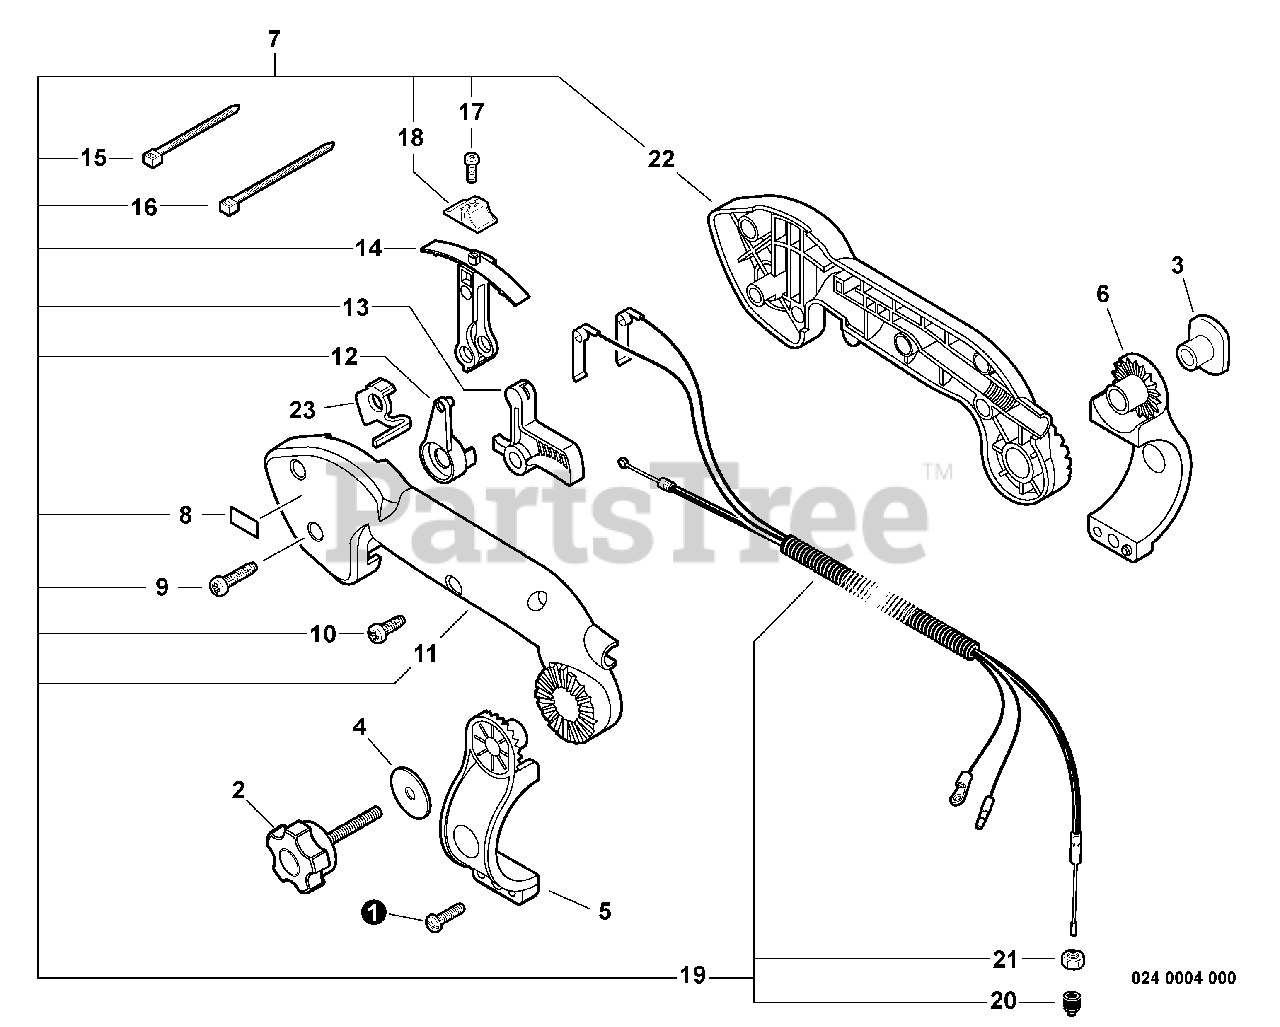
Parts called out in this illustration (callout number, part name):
1	SCREW, TAPPING 5×20
2	KNOB, SCREW
5	BRACKET, HANDLE - LEFT
6	BRACKET, HANDLE - RIGHT
7	CRUISE CONTROL KIT
8	LABEL, CAUTION - IDLE
11	HANDLE, FRONT - LEFT
12	LEVER, THROTTLE
13	TRIGGER, THROTTLE
14	LEVER, CRUISE CONTROL
15	STRAP, TIE
16	STRAP, TIE - LARGE
17	SCREW 3×14
18	KNOB, CONTROL
19	CONTROL CABLE ASSY
20	CAP, DUST
21	NUT, HEX M6
22	HANDLE, FRONT - RIGHT
23	GUARD, CONTACT
